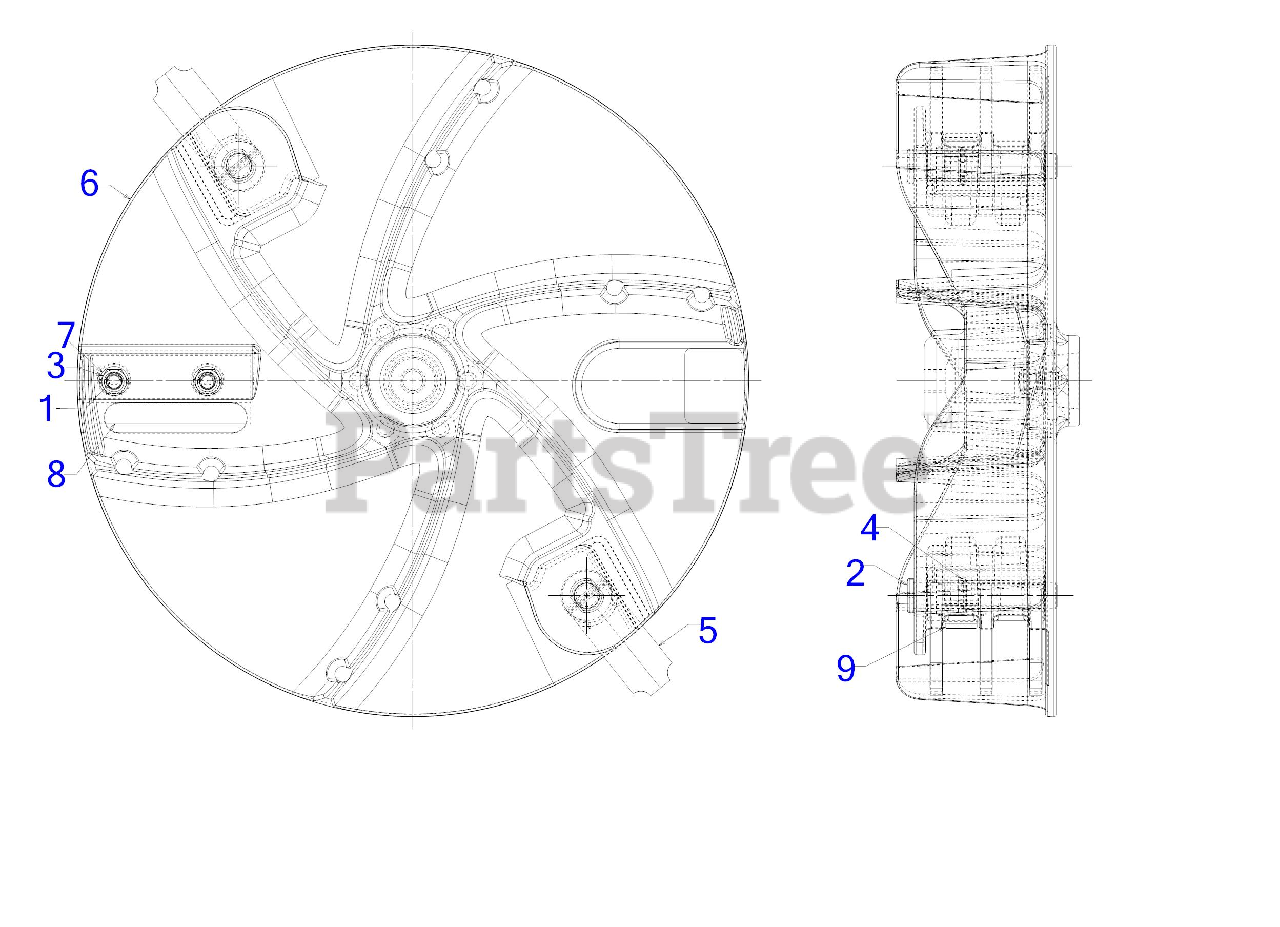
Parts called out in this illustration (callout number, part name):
1	SCREW 5/16-24 x 1
2	CLEVIS PIN DIA .49
3	HEX NUT
4	PIN SPIROL .156X1
5	FLAIL BLADE
6	IMPELLER ASSEMBLY
7	LOCK WASHER 5/16
8	CHIPPER BLADE
9	RETAINING PIN CLIP
